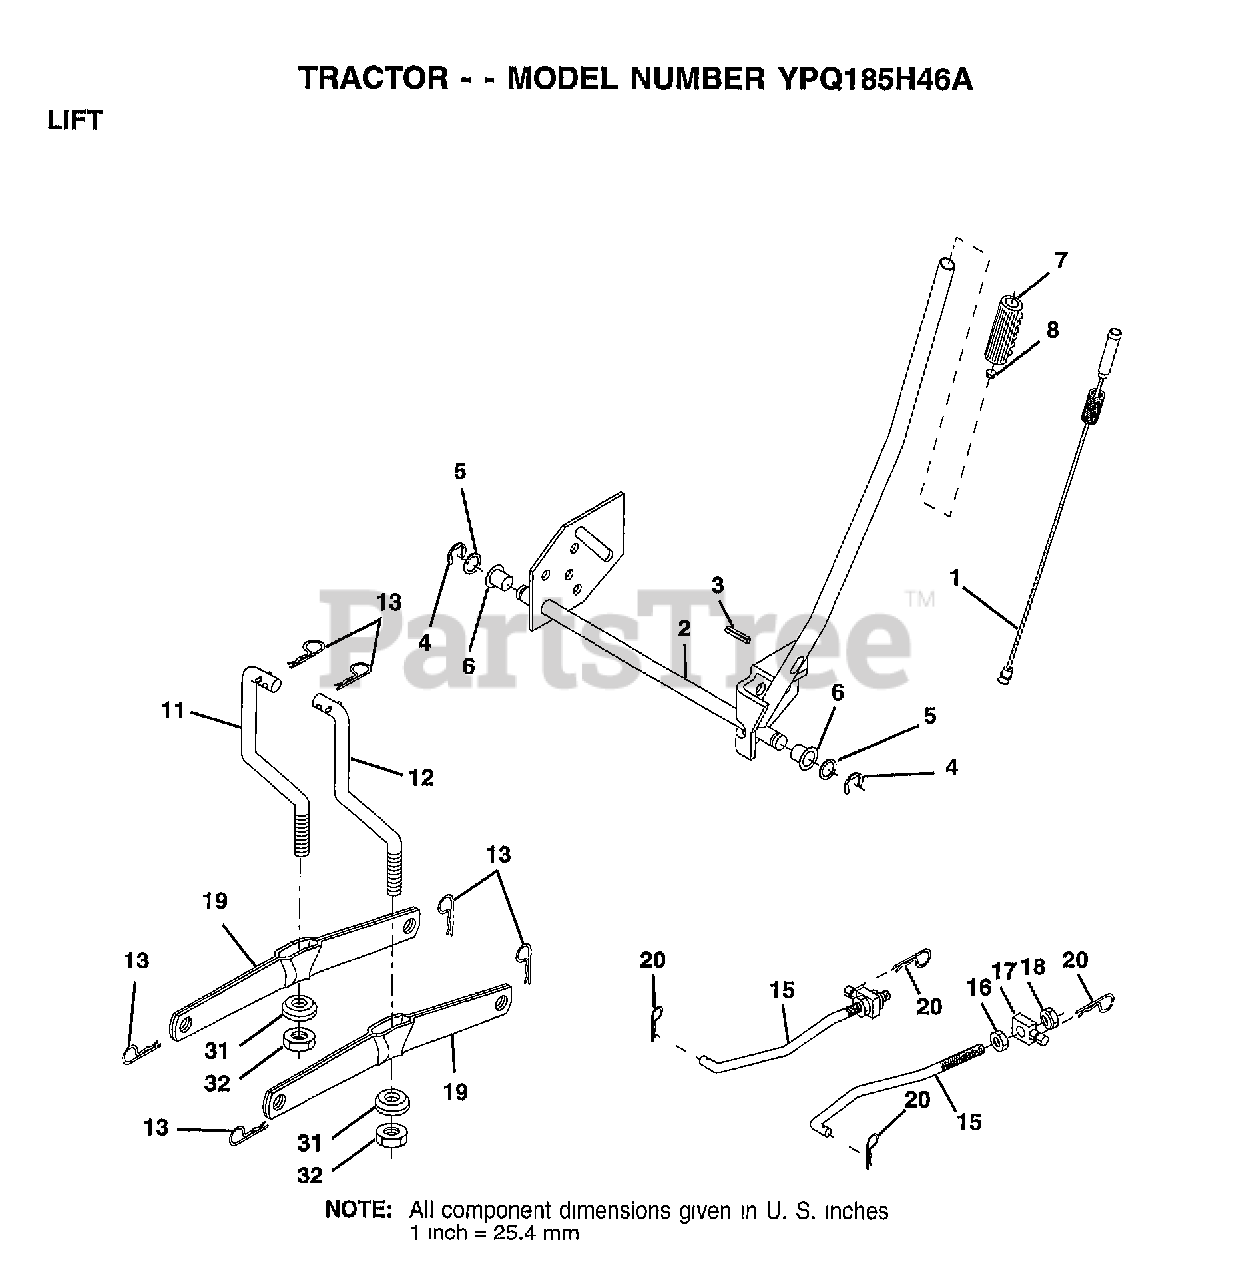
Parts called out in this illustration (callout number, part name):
1	WIRE ASM W.SPRING
2	"SHAFT ASM LIFT,RH"
3	PIN-GROOVE LT
5	WASHER
6	NYLON BEARING
7	GRIP HANDLE
15	LINK.FRONT
16	NUT
17	TRUNION
18	NUT LTV
19	ARM SUSP REAR
20	RETAINER SPRING
31	BEARING PVT LH
32	NUT.CROWNLOCK.3/8
